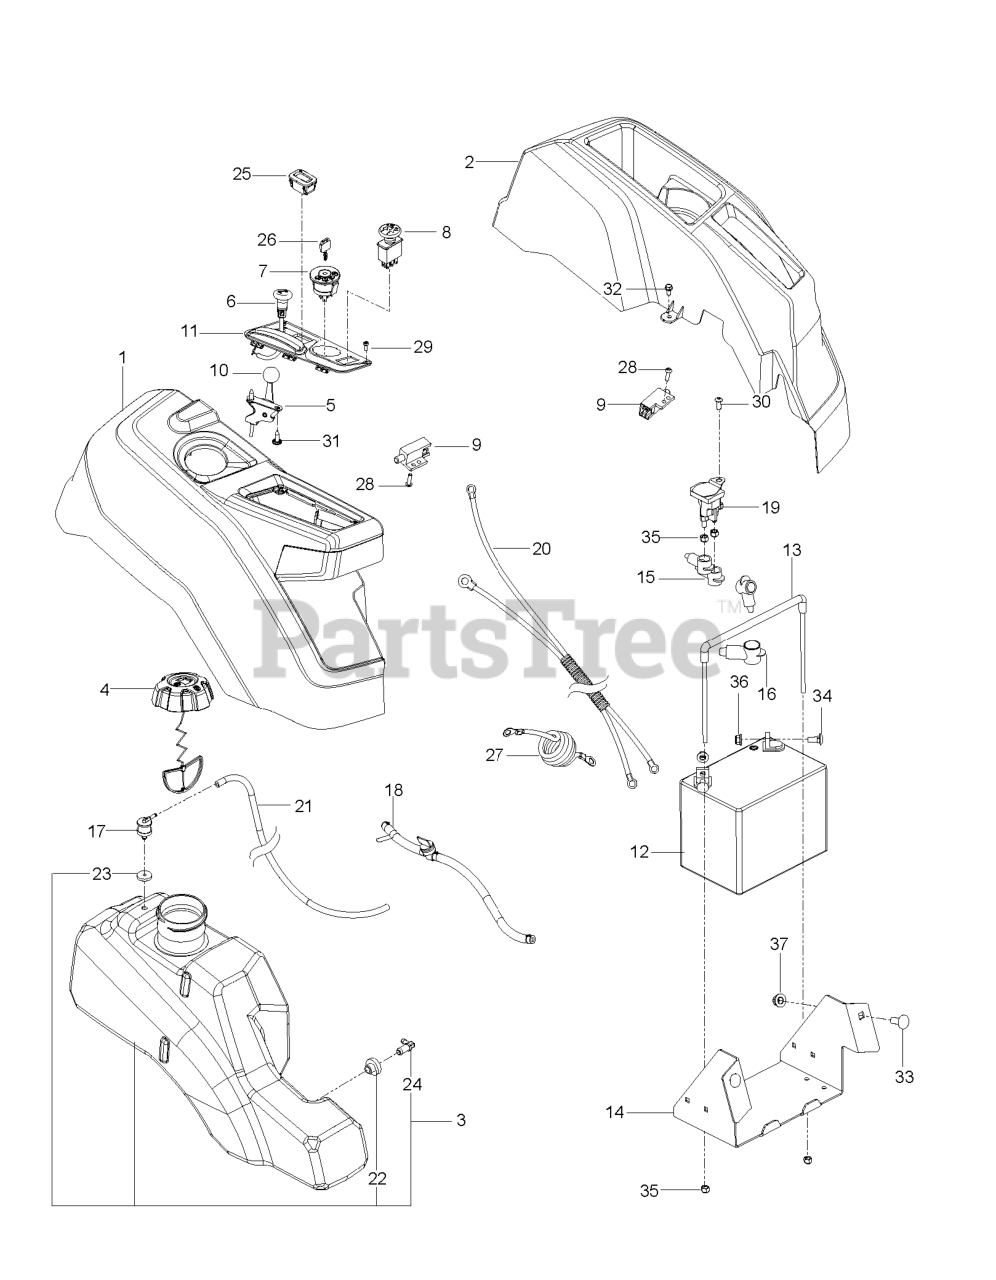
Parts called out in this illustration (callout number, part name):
1	CONSOLE.ASSY.RZ.REFRESH.RH
2	CONSOLE.LH.ASM
3	ASM.FUEL.TANK.LG.3".W/O SHIELD
4	CAP ASSY FUEL 3" GRAY
4	FUEL CAP
5	THROTTLE CONTROL W/BALL KNOB
6	CHOKE.PUSH-IN.STYLE.57"
7	RP IGNITION SWITCH
8	RP SWITCH.PTO.8.TERMINAL.RED
9	SWITCH.INTLK.RZ.RFRSH.BUTTON
10	KNOB.ROUND.BALL.BLACK
11	CONTROL.PANEL.RZ.REFRESH.RH
12	BATTERY, 12 V 330 AMP
13	BATTERY TIE DOWN ASSEMBLY
14	BOX BATTERY RZ BLACK
15	TERMINAL COVER
17	VALVE.FUEL.CHECK
18	FUEL.HOSE.SHUT.OFF.ASM.10".3"
19	SOLENOID.W/BRASS.PLUNGER
20	HARNESS.BTTRY.CABLE.RZ.REFRESH
21	HOSE.3/16".VAPOR.LINE.33"LGTH
22	BUSHING OUTLET T
23	GROMMET.ROV.SENTEC
24	STEM FUEL TANK
25	GUAGE.SRVCMNDR.HRMTR.
26	KEY MLD GEN DELTA
27	CABLE POSITIVE, LONG
28	SCR #10-24 X .75 SKT HD BLK
29	SCREW 6-19X.437
30	SCR 1/4-20 X 5/8 BTN SKT HD ZD
31	SCREW.PAN.HEAD.#10
32	SCREW
33	RHSNB 3/8C X 1
34	RP BOLT 5/16-18 X3/4 ZN/YEL GR
35	LOCKNUT.NYLOC.1/4-20
36	5/16-18 NYLOC FLANGE NUT
37	NUT 3/8-16 HEX FLG NYLOC ZD
